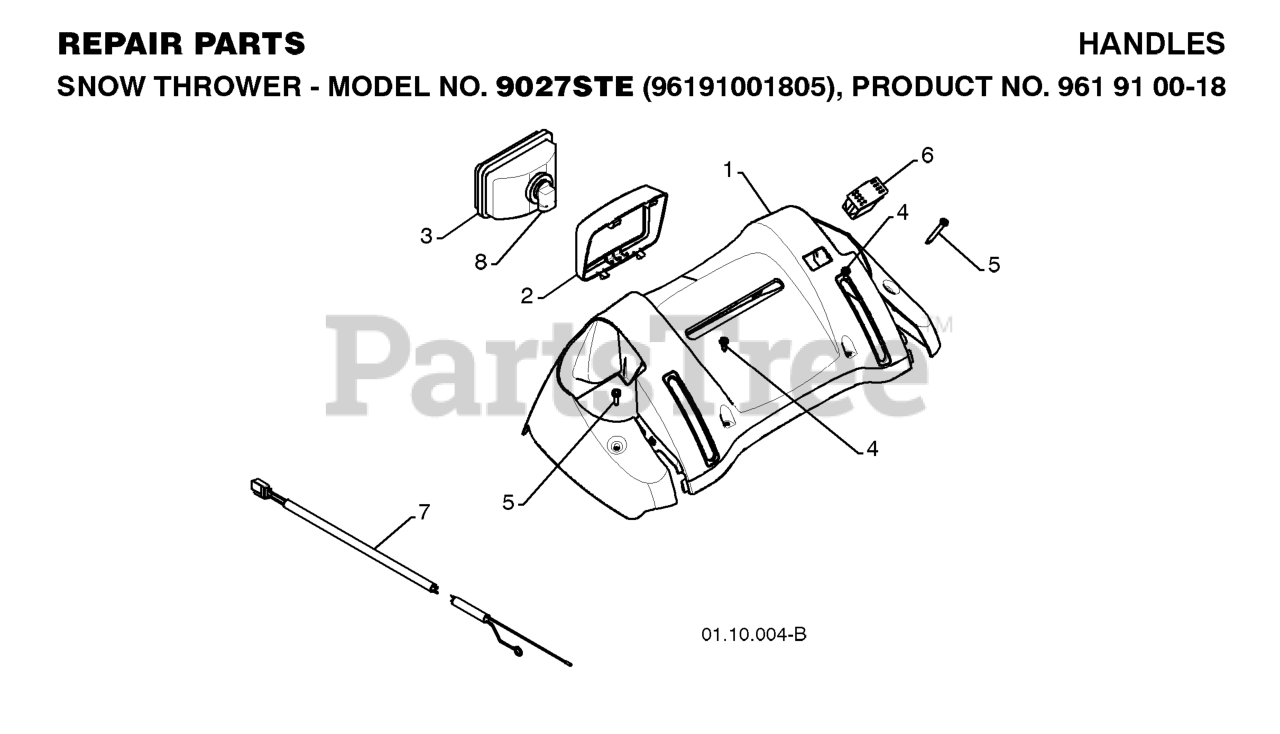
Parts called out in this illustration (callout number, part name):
1	PANEL.CONSOLE.LIGHT.REM.SWITCH
2	BEZEL.HEADLIGHT.BLACK
3	HEADLIGHT.HALOGEN.SNOW
4	SCREW, HEX HEAD, TAPPING
5	SCREW, HEX HD TAPPING #10-24 1
6	SWITCH.HEATED.GRIP
7	HARNESS.WIRE.LIGHT/GRIP.SNOW
8	BULB.HEADLIGHT.HALOGEN.
